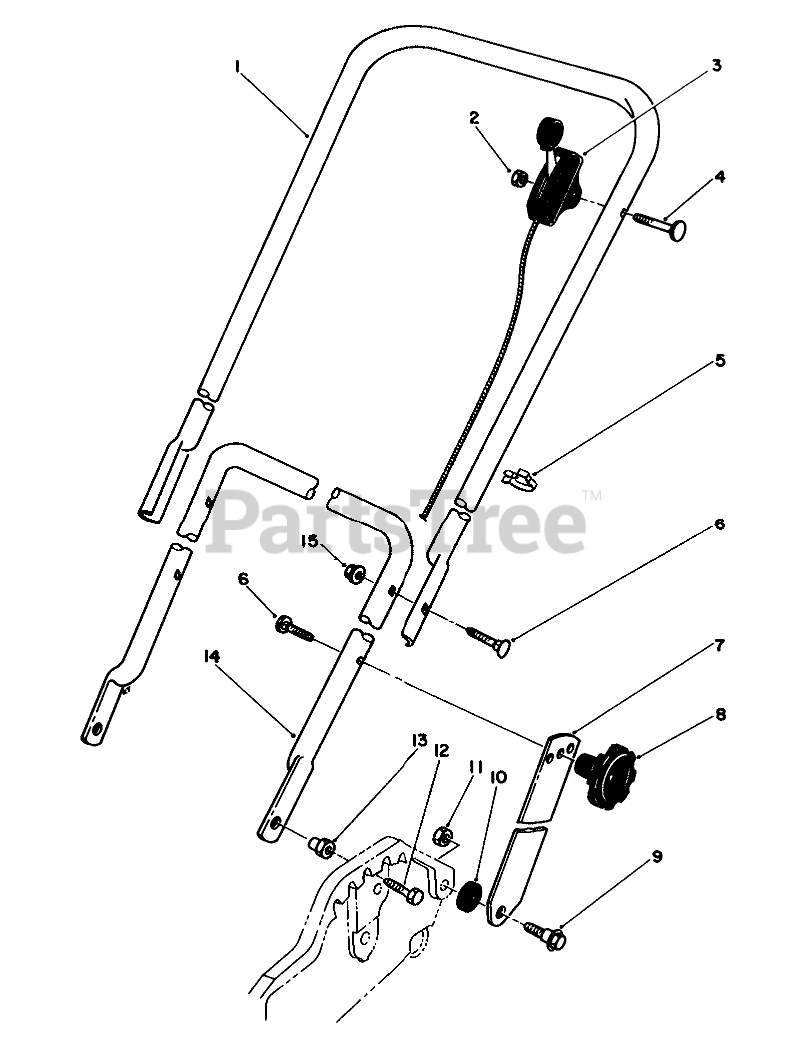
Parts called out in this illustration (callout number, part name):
1	Handle-Upper
2	NUT-LOCK, NI
3	SERVICE THROTTLE CONTRO
4	SCREW-HANDLE
5	BOWDEN CLIP
6	SCREW
7	Handle Latch
9	SCREW-SHOULDER
10	SPACER
11	NUT-LOCK, NI
12	SCREW-HH
13	HANDLE PIVOT NUT
14	LOWER HANDLE
15	NUT-LOCK, NI
